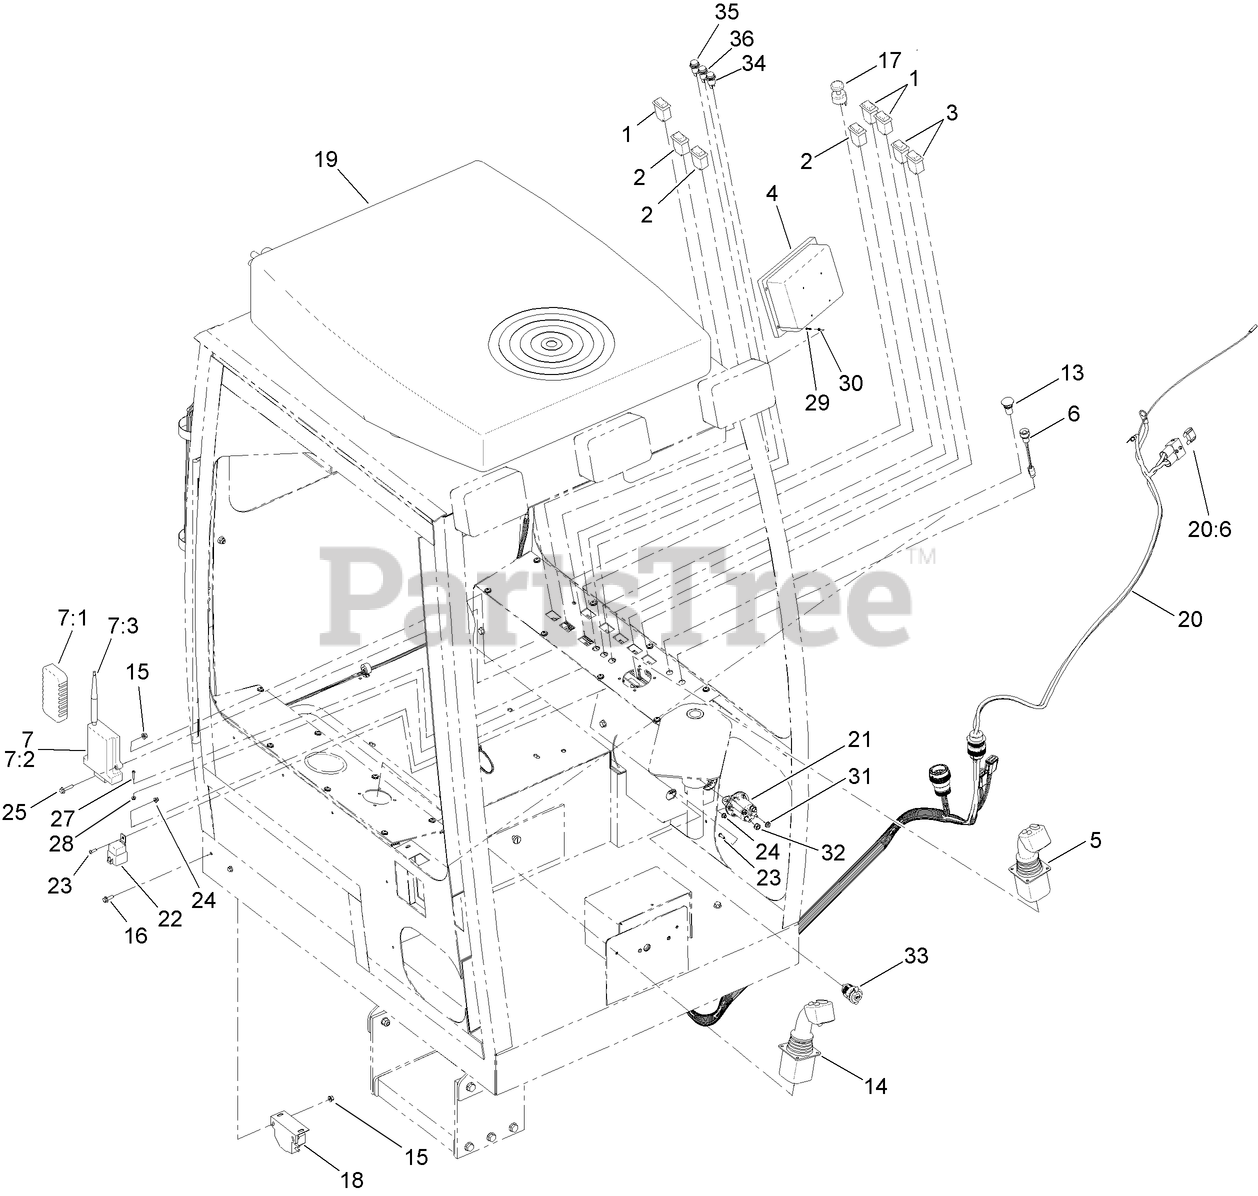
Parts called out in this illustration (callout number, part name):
1	SWITCH-ROCKER, 2 POLE (ON/OFF)
2	SWITCH-ROCKER, 2 POLE
3	SWITCH-ROCKER, 1 POLE (ON)OFF/ON(OFF)
4	DISPLAY-DP600, UNPROGRAMMED
5	JOYSTICK-MODIFIED (LEFT HAND)
6	SWITCH-START, GREEN BUTTON
7	LONG RANGE EXIT SIDE LOCKOUT KIT
7:1	HANDHELD-LOCKOUT
7:2	BASE UNIT-LOCKOUT
7:3	ANTENNA-LOCKOUT
13	BUTTON-PUSH, RED MUSHROOM
14	JOYSTICK-CARRIAGE
15	NUT-FLANGE, NI
16	SCREW-HHF
17	SWITCH-WIPER
18	ALARM-BACKUP
19	HARNESS-WIRE, CAB
20	HARNESS-WIRE, CAB POWER
20:6	FUSE-MAXI, 60 AMP
21	SOLENOID
22	RELAY
23	SCREW-HSBH
24	NUT-HF
25	SCREW-HHF
27	SCREW-HSBH
28	NUT-HHF
29	SCREW-PRH, SLOTTED
30	NUT-LOCK, NI
31	NUT-KEPS
32	NUT-KEPS
33	RECEPTACLE-12V
34	LAMP-INDICATOR, LED
35	LAMP-INDICATOR, LED
36	LAMP-INDICATOR, LED
